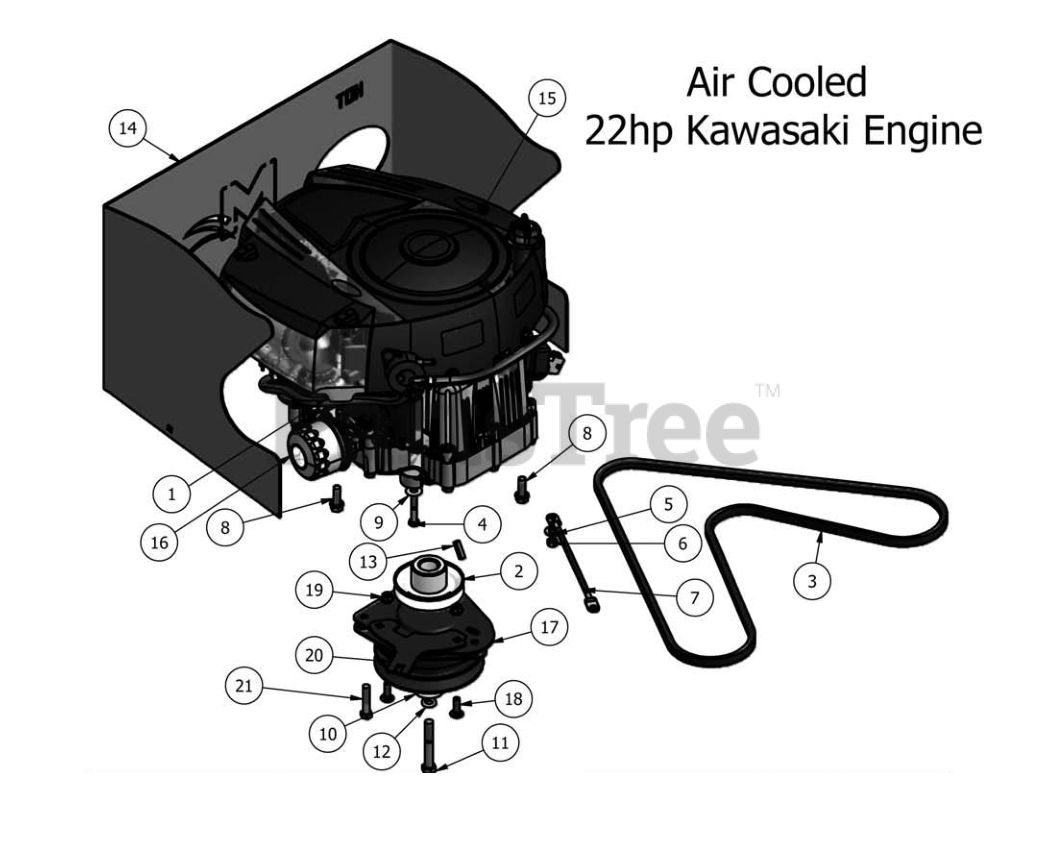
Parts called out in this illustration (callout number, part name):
1	22 hp Kawasaki
2	3-3/4" Motor Pulley
4	3/8 x 3 1/2 Grade 5 Hex Bolt Clutch Stop
5	5/16 Lock Washer Zinc
6	5/16-18 Hex Nuts Zinc
7	Ground Cable
8	3/8 x 1-1/8 Hex Washer Head Engine Bolt
9	5/16 USS Flat Washer Zinc
10	Spring Blade Cupped Washer
11	MZ Crank Shaft Bolt
12	7/16 Lock Washer Zinc
13	1/4" x 1" Key
14	Engine Rear Plate
15	Air Filter 22Hp MZ
16	Oil Filter 22Hp MZ
18	5/16" x 1" Carriage Bolt
19	5/16" Flange Nut
20	clutch Holder
21	3/8-16 x 3 1/2 Hex Bolt
